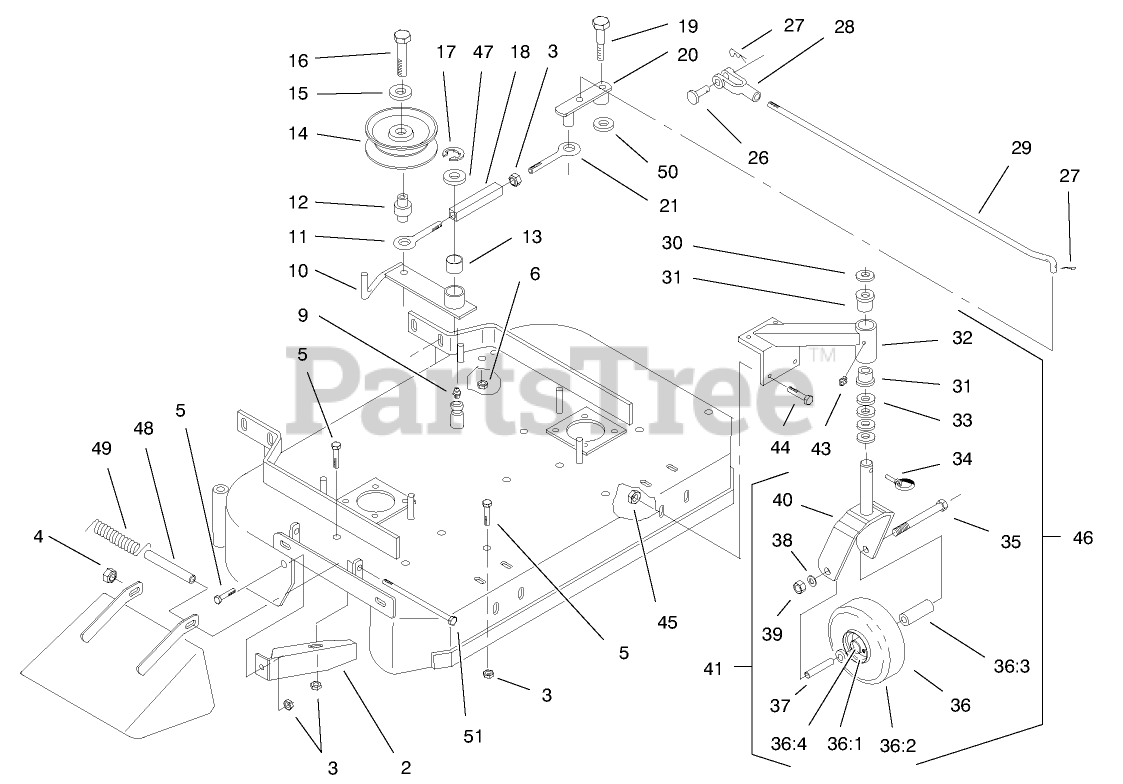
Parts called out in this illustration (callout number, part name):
2	Baffle
3	NUT-HF
4	NUT-LOCK, NI
5	Screw-HH
6	NUT-HF
9	FITTING-STRAIGHT
10	Engagement Arm w/Bushing
11	Eye Bolt
12	Bushing
13	Bearing
14	Pulley-Idler
15	WASHER-FLAT
16	Bolt-Whizlock
17	Ring-Snap
18	Turnbuckle Body
19	Bolt-Shoulder
20	Assist Arm ASM
21	Eye Bolt
26	Pin-Clevis
27	PIN-COTTER
28	Yoke
29	Linkage-Assist Arm
30	Washer
31	Bearing-Flanged
32	Support-Caster
33	Spacer
34	Pin
35	SCREW-HH
36	Tire and Wheel ASM
36:1	Wheel Hub ASM
36:2	Tire
36:3	Bearing
36:4	Bushing
37	Spacer
38	WASHER-LOCK
39	NUT-HH
40	Fork
41	Caster Wheel ASM
43	Zerk
44	SCREW-HH
45	NUT-FLANGE
46	Caster/Mount ASM
47	Spindle Washer
48	Spacer
49	Spring-Deflector
50	WASHER-THRUST
51	Screw-HH
